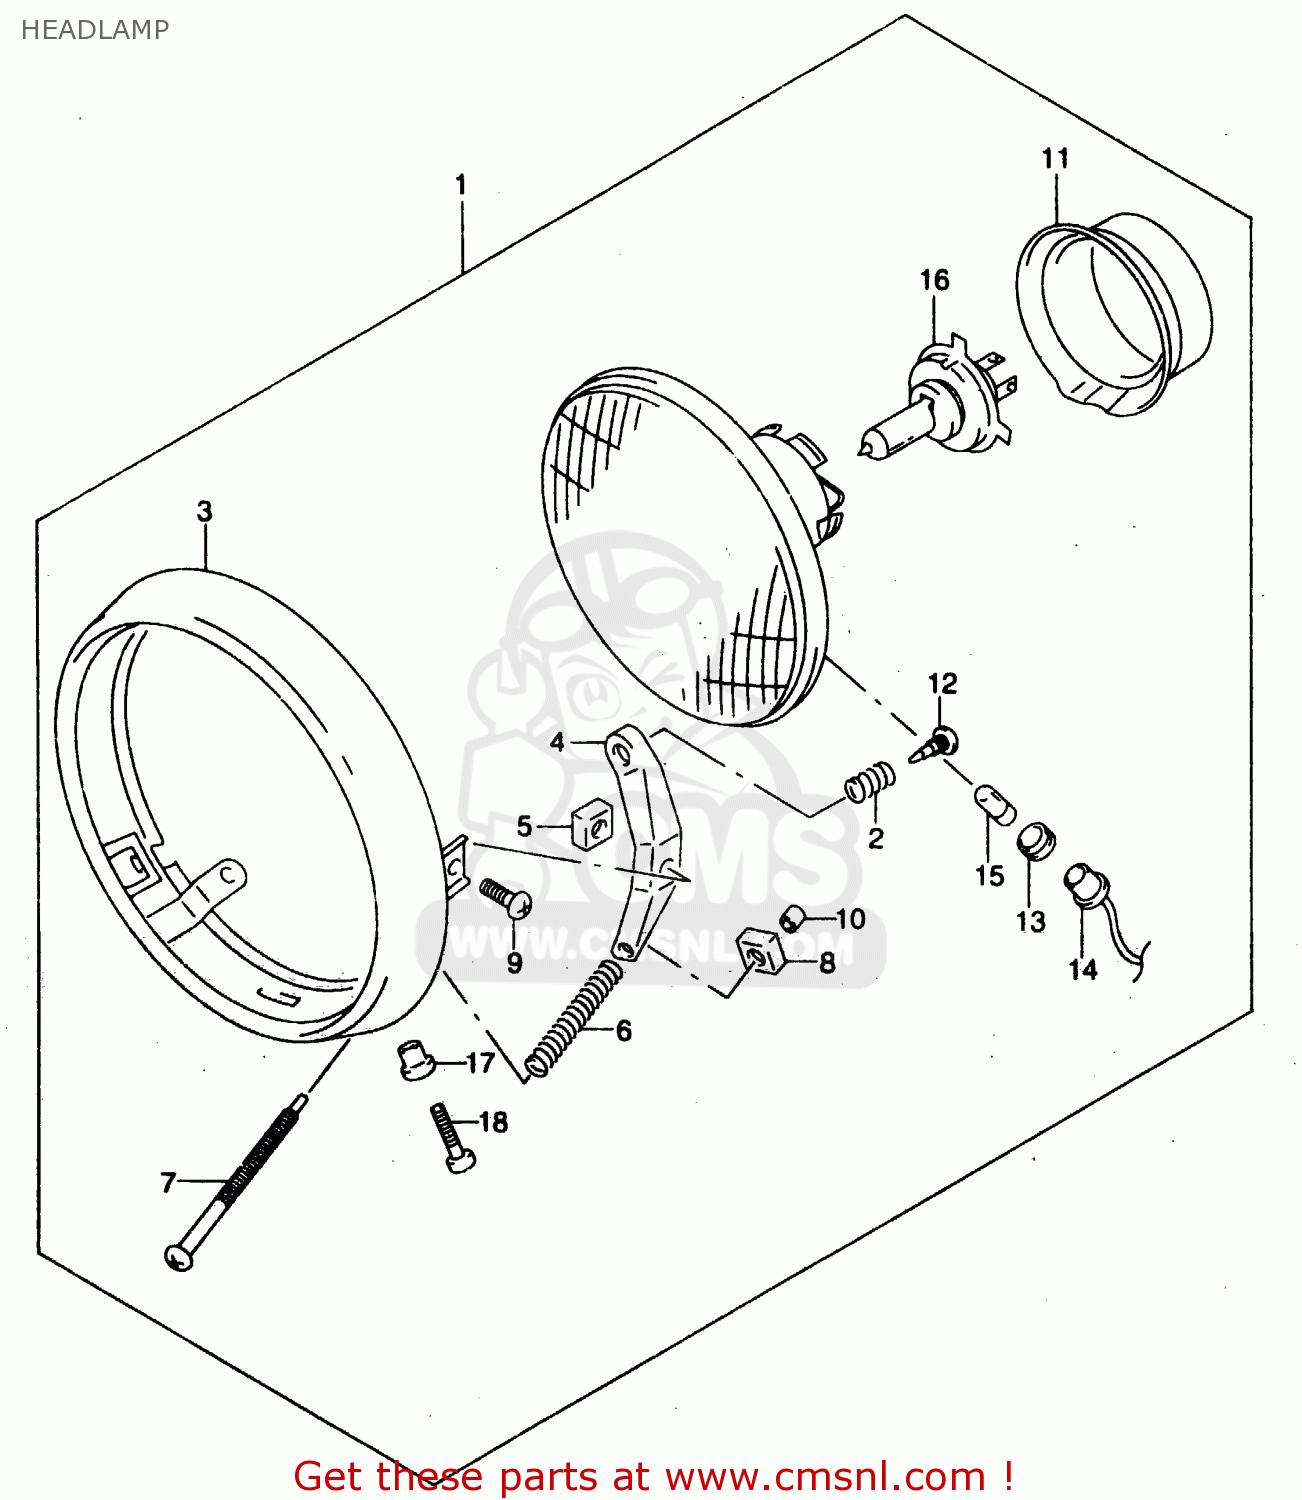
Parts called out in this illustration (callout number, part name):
1	HEADLAMP ASSY
2	SPRING
3	RIM,HEAD LAMP
4	STAY
5	NUT
6	SPRING
7	ADJUSTER SCREW
8	NUT,HEADLAMP ADJUST
9	SCREW
10	CAP,SCREW
11	COVER,SOCKET
12	SCREW
13	JOINT,RUBBER
14	CORD,POSITION
15	BULB(12V4W)
16	BULB(12V60/55W,H4)
17	SPACER,HEADLAMP
18	SCREW
